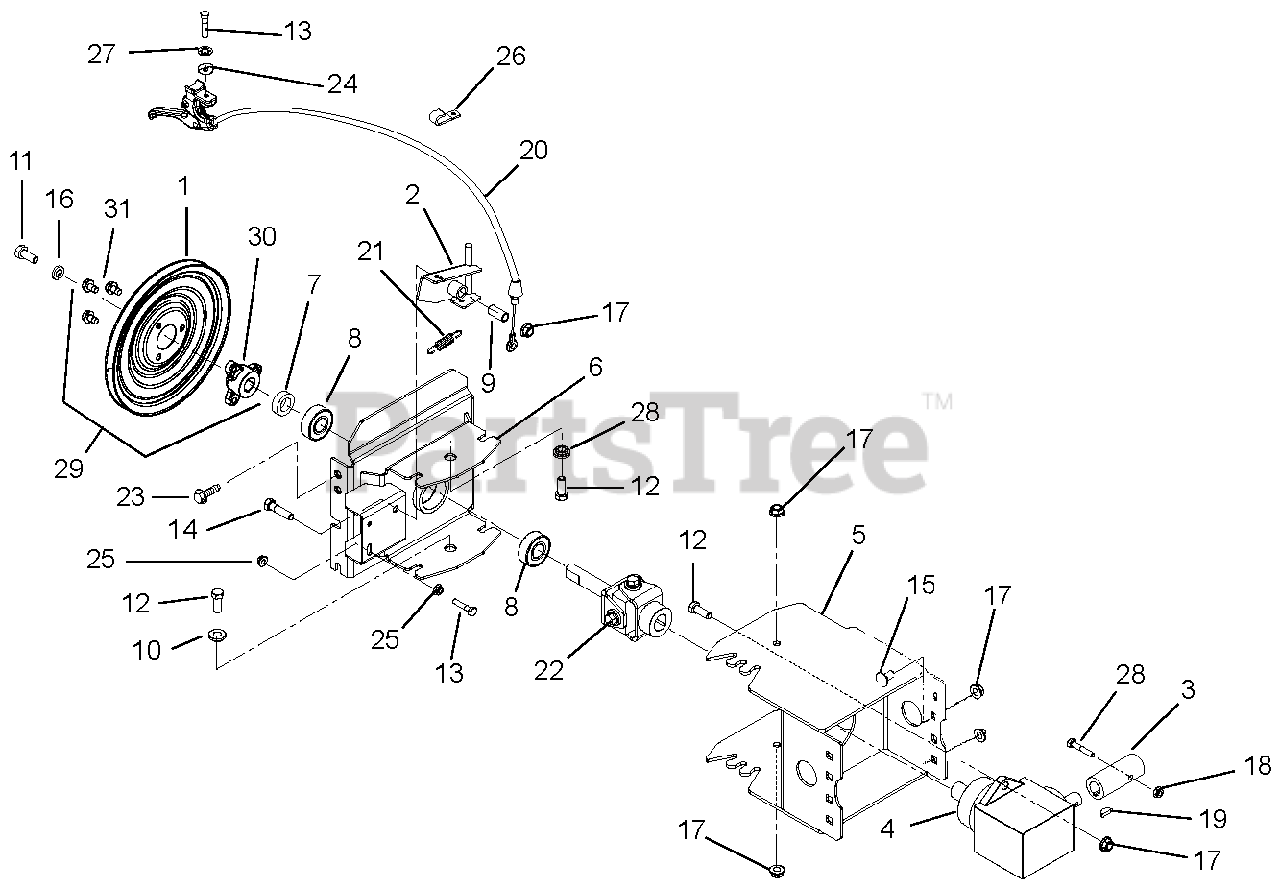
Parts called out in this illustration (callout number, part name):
1	Pulley, Single Groove
2	Arm, Pivot Lock
3	Hub, Coupling
4	Gear Box Assembly
5	Adapter with Decal, Brush Frame
6	Adapter, Broom Frame - 20000 Series
7	Spacer, .755 x 1.250 x .370
8	Bearing, Ball .750 x 1.781 x .61
9	Bushing, Sleeve .385 x .500 x 1.045
10	Bushing, Flange .406 x .88 x .270 x .140
11	Bolt, Hex .31-24 x .75 Grade 5
12	Bolt, Hex .38-16 x 1.00 Grade 5
13	Bolt, Hex .25-20 x 1.50 Grade 5
14	Bolt, Hex .38-16 x 1.75 Grade 5
15	Bolt, Round Head Square Neck .38-16 x .75 Grade 5
16	Washer, Locking .312 x .097 Heavy
17	Nut, Locking-Top-Flange .38-16
18	Nut, Locking-Top-Flange .25-20
19	Key, Woodruff .188 x .75 x .313 SAE 9
20	Cable, Remote Brush Lock
21	Spring, Tension .06 x .46 x 2.00
22	Universal Joint Assembly
23	Screw, Tapping .31-18 x .75 Hex Washer Head
24	Spacer, Handlebar
25	Nut, Locking Flange .250-20
27	Washer, Locking-Internal .250
28	Bolt, Hex .25-20 x 1.75 Grade 5
29	Pulley Assembly (Includes items 1, 30, 31)
30	Hub, Pulley, 0.75 Bore
31	Screw, Tapping, .31-18 x .50
